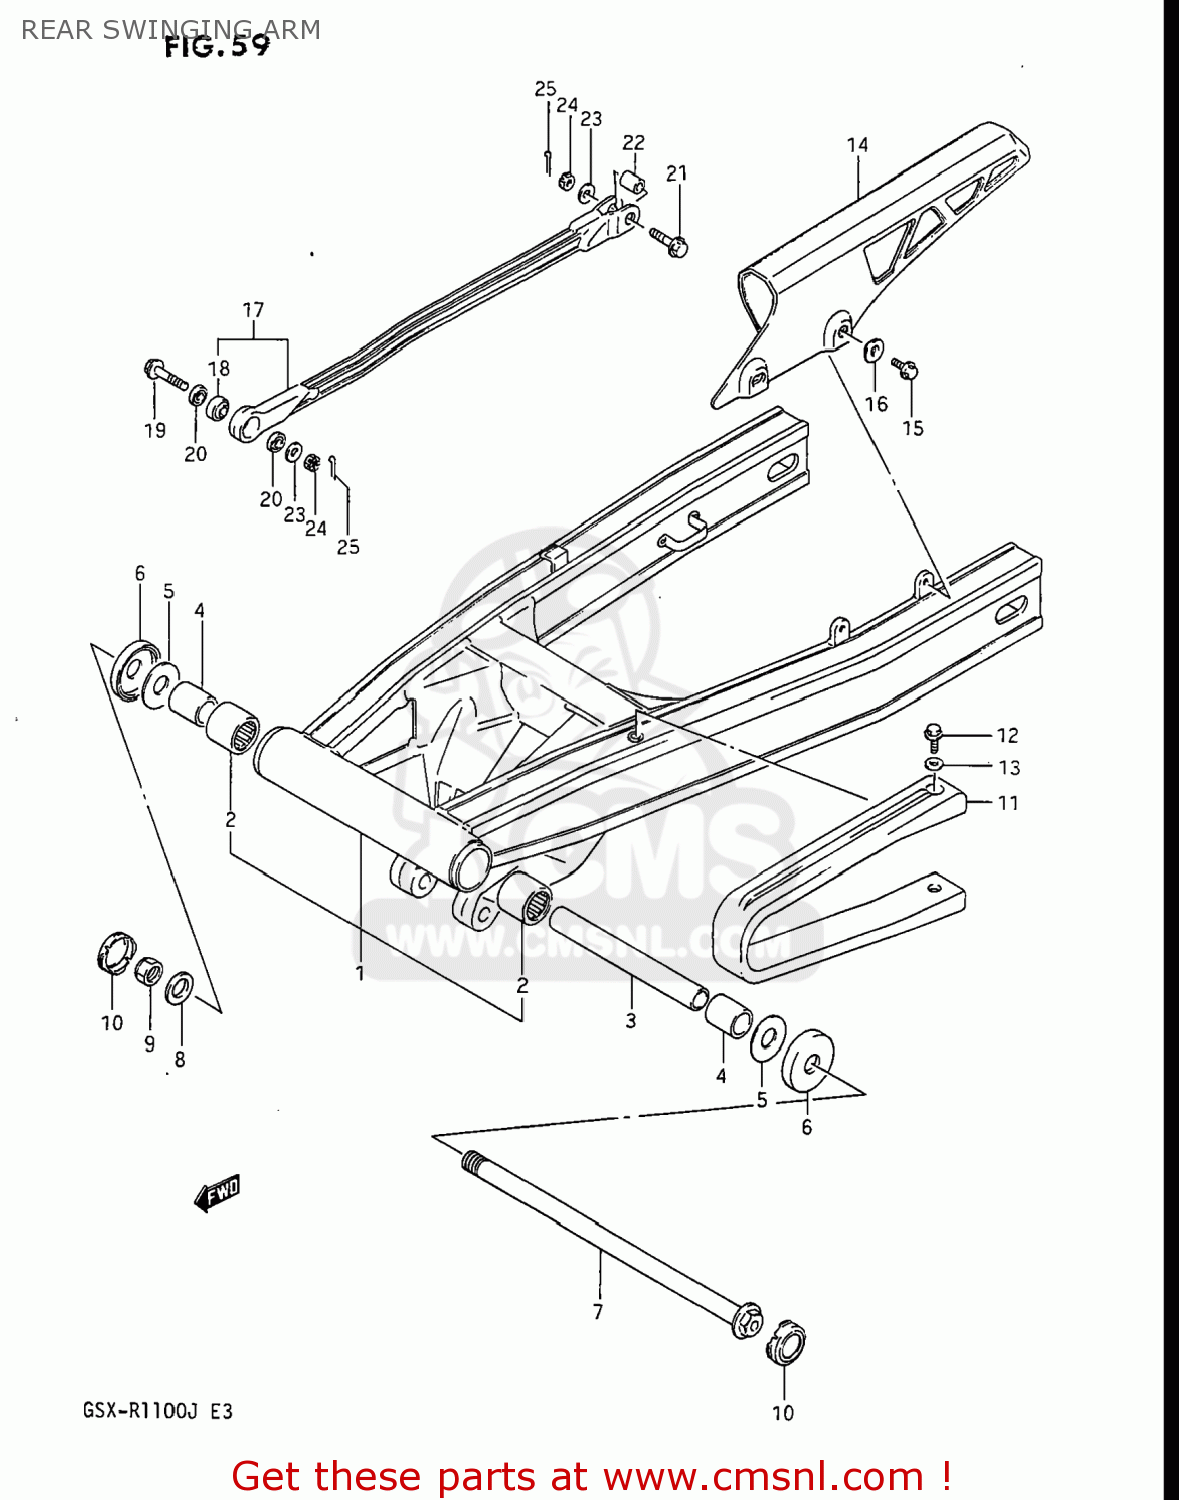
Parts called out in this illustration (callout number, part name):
1	ARM,REAR SWING
2	BEARING(25X33X30)
3	SPACER,REAR SWING ARM PIVOT
4	SPACER,RR SWGARM PIVOT
5	WASHER
6	COVER,RR SWINGINGARM PIVOT
7	SHAFT,RR SWINGINGARM PIVOT
8	WASHER(14X27X3)
9	NUT
10	CAP,SWINGINGARM PIVOT
11	BUFFER,CHAIN TOUCH DEFENSE
12	BOLT,REAR
13	WASHER
14	CASE,CHAIN
15	BOLT
16	WASHER
17	TORQUE LINK SET,REAR
18	SPHERICAL BEARING,TORQUE
19	BOLT
20	21
21	BOLT
22	SPACER,RR TORQUE LINK RR
23	WASHER
24	NUT 8MM
25	PIN 20X20
